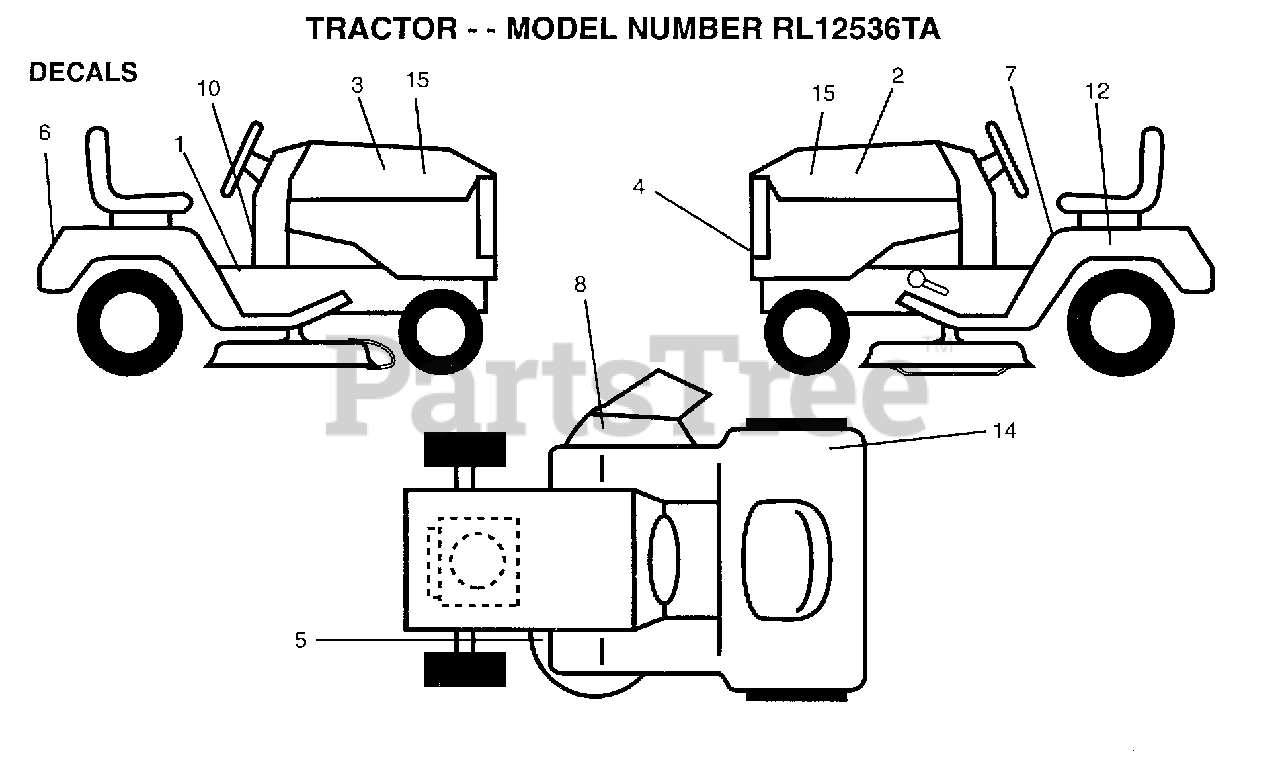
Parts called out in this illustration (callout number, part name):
1	DECAL.OP.INST.SYM
2	DECAL HD RLY LH
3	DECAL HD RLY RH
4	GRILL DECAL
5	DECAL.V.BELT
6	FENDER DECAL
7	DECAL.READ.O.MANU
8	DECAL.DANGER.CUTF
10	DECAL.EURO.ST.CE.
12	DECAL.BTRY.DANGER
15	DECAL.INS.HD.12.5
